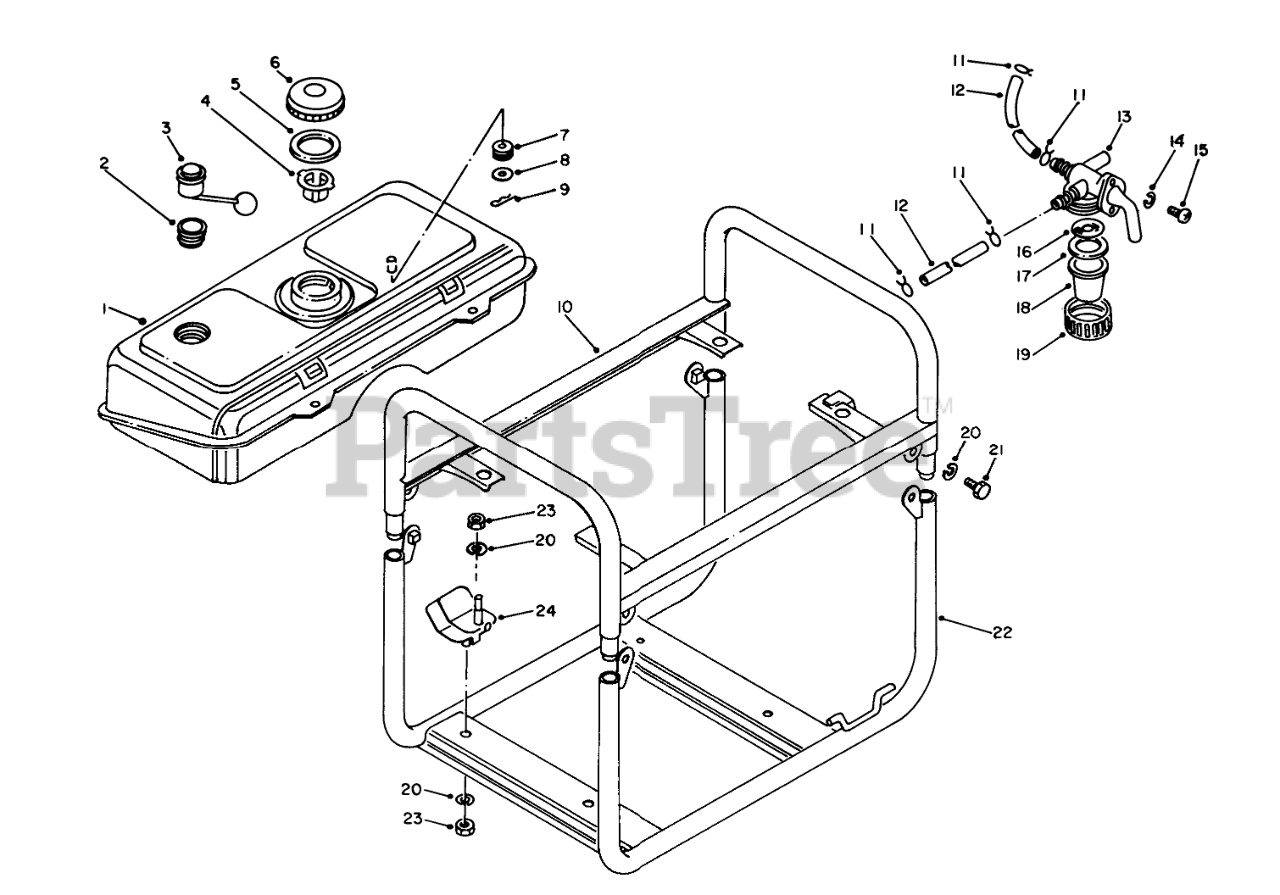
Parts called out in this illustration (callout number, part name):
1	Tank-Fuel
2	Gasket
3	Gauge Assembly-Fuel (Incl. Ref. #6)
4	Filter
5	GASKET
7	CUSHION
8	WASHER
10	Frame-Upper
13	Cock Assembly-Fuel (Incl. Ref. #16-19)
14	Lockwasher
15	Screw
16	FILTER
17	GASKET
20	WASHER-LOCK
22	Frame-Lower
23	Nut
24	Engine Mount
